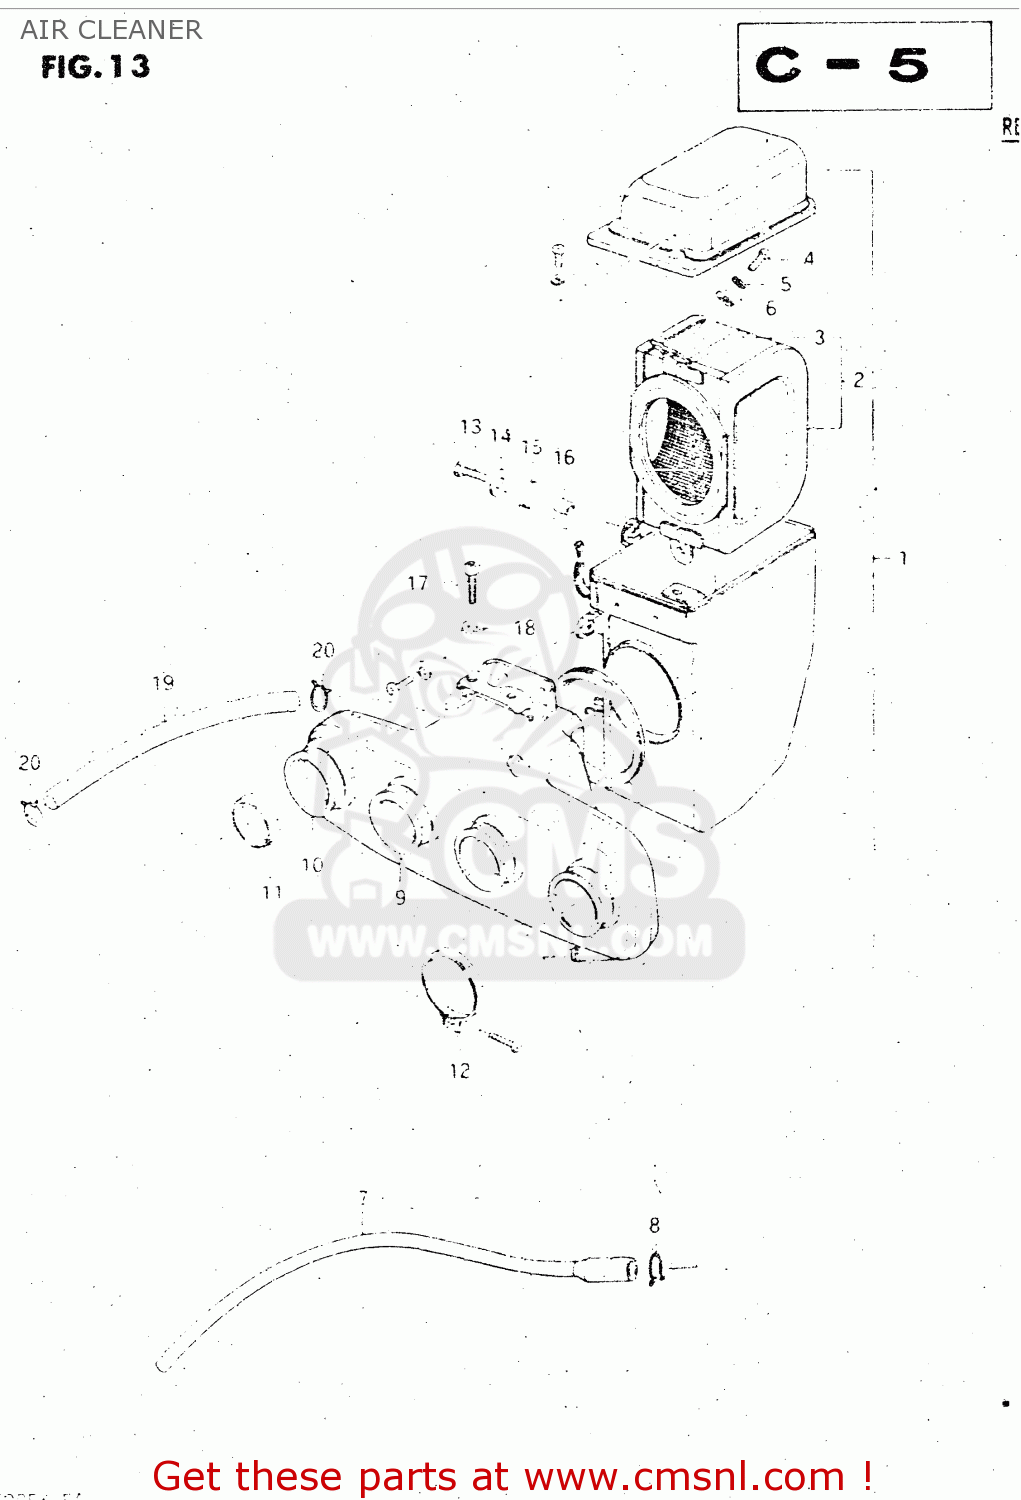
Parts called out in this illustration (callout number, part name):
1	CLEANER ASSY, AIR
2	FILTER ASSY
3	FILTER
4	SCREW
5	LOCK WASHER
6	WASHER
7	DRAIN TUBE
8	CLIP
9	TUBE,OUTLET,INNER
10	TUBE,AIR CLEANER OUTLET B
11	RING,CARBURETOR AIR INLET HOSE
12	CLAMP
13	BOLT
14	WASHER
15	CUSHION
16	SPACER (6.1X9X9)
17	SCREW 6X12
18	WASHER
19	HOSE
20	CLIP
